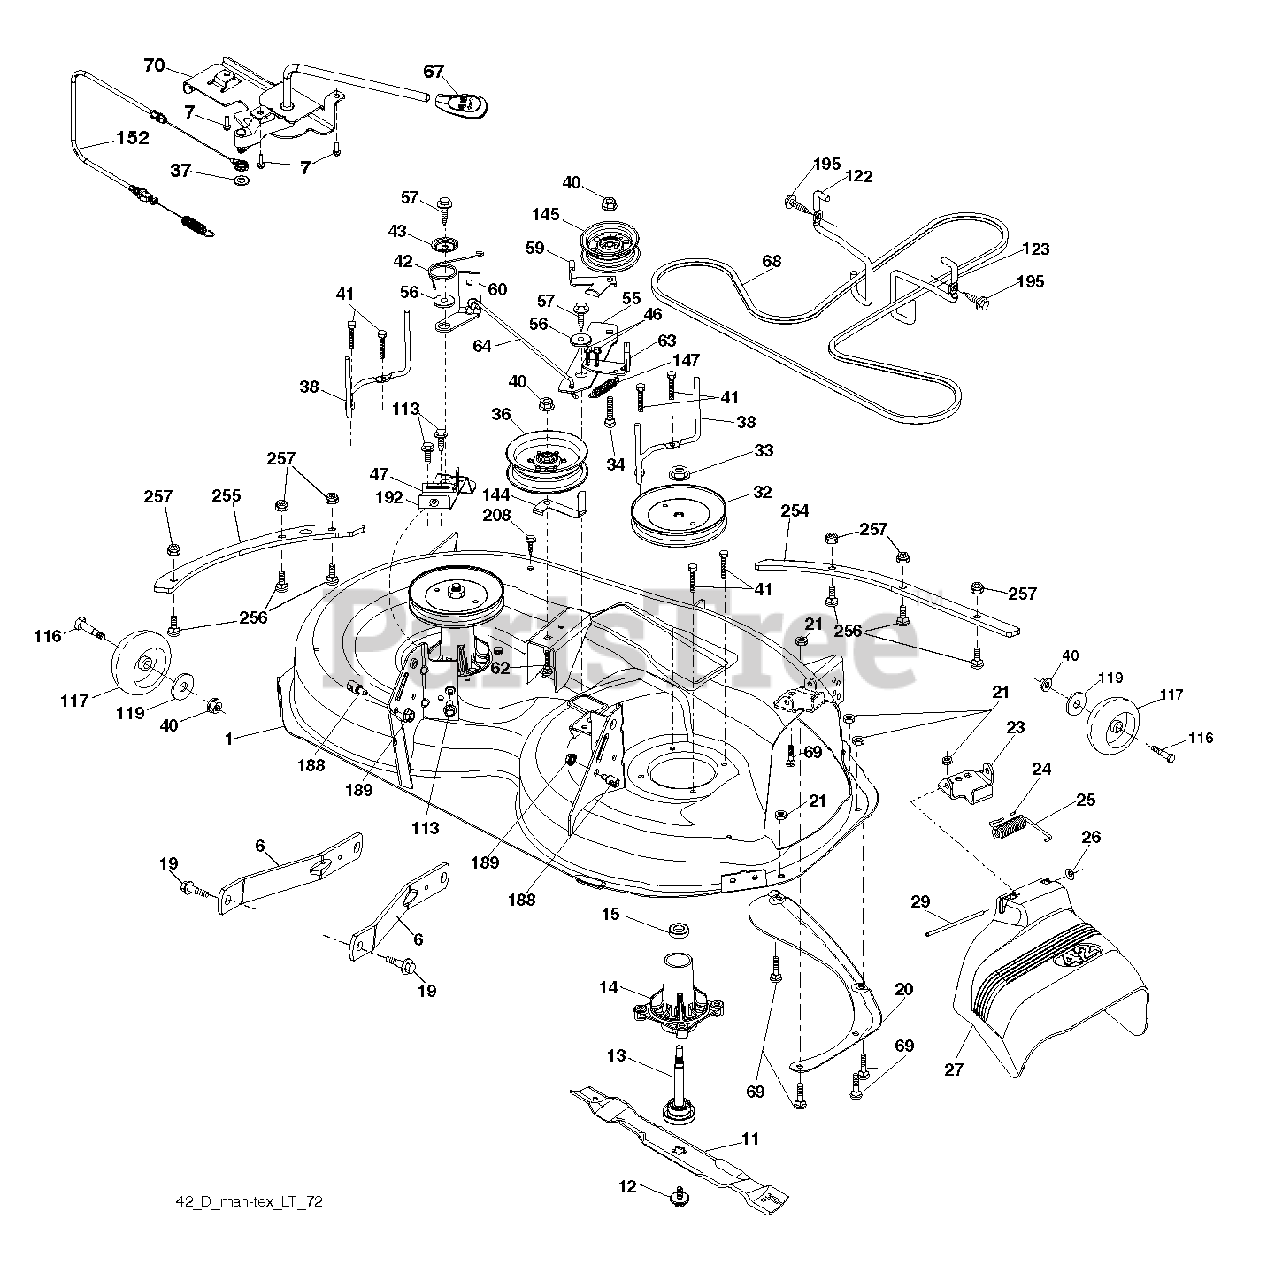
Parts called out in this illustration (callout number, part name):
1	Mower Deck Assembly, 42"
6	ARM.SUSPENSION.MOWER.R
7	SCREW.#10 X 0.750.BOS (2 2)
11	42" HI-LIFT BLADE
12	Screw, 7/16 X 20 X 1"
13	SHAFT.ASM.MDRL.N/GREASE.38
14	HOUSING.MANDREL.4PT.
19	BOLT.SHOULDER
20	BAFFLE.VORTEX
21	LOCKNUT
23	BRKT.DEFLECTOR.38"2005+
24	CAP-SLEEVE LT
25	SPRING.TORSION.DEFLECT
26	NUT PUSH M
27	SHIELD.DEFLECTOR.MOWER.42"BLAC
29	ROD.HINGE
32	PULLEY.MANDREL.5.438.PD
33	NUT.FLANGE.LOCK.TOP
34	BOLT.3/8-16X1.50
36	PULLEY.IDLER.2006
38	KEEPER.BELT.MANDREL.PULLEY
40	NUT LOCK FLG 3/8-16 UNC
41	Hex Washer Head Bolt, .313-18 X 1.19
42	SPRING.TORSION.BRAKE
43	SRPING.TORSION.RETAINE
46	SCREW.1/4-20X5/8
47	BRKT.CLUTCH.CABLE
55	IDLER.ARM.42"
56	SPACER.RETAINER
57	SCREW 3/8-16X1
59	GUARD, BELT
60	ARM BRAKE MOWER
62	BOLT
64	LINKAGE.BRAKE.ASM.ZINC
67	HANDLE.CLUTCH.CABLE.LT
68	BELT.DECK.DRIVE.42"
69	BOLT
70	CLUTCH.ASM.MANUAL.LT.PRED
113	BOLT.5/16HEX.WHS.HD
116	BOLT M
117	WHEEL.GAGE.HALF.SPOKED
119	WASHER
122	KEEPER BELT ENGINE LH
123	KEEPER BELT RH
144	KEEPER.BELT.MOWER
145	PULLEY.IDLER.48"PRIMARY
147	RETURN SPRING
152	CABLE.MECHANICAL.CLUTCH
188	STUD.FASTNER.W/ANTI-ROTATE
189	NUT LOCK HEX FLANGE 5/16-18
192	BRKT.BRAKE.STAND.LH.
195	SCREW, 3/8-16X3/4
208	SCREW 3/8-16X1/2
254	Front Reinforcement Plate, 42" Deck.Ftx498
255	Side Reinforcement Plate, 42"
256	RHSNB, 1/4-20 X 1, GR5
257	NUT T
